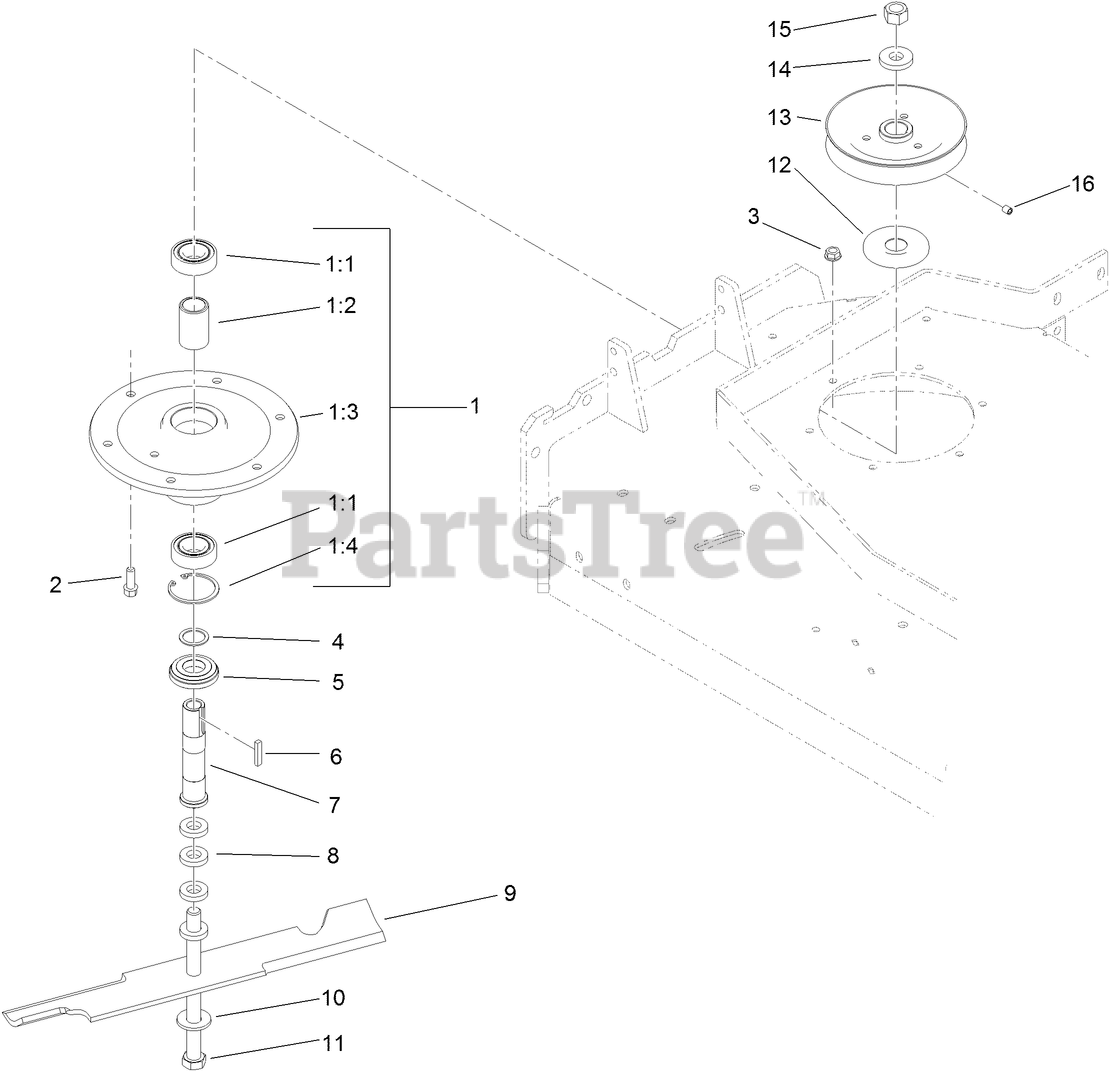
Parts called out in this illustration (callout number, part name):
1	SPINDLE HOUSING ASM
1:1	BEARING-BALL, 1 INCH
1:2	SPACER-BEARING
1:3	HOUSING-SPINDLE
1:4	RING-SNAP
2	SCREW-HWH
3	NUT-HF, NI
4	WASHER-SPACER
5	SPACER-GUARD, BOTTOM
7	TUBE-SPINDLE, SHORT
8	SPACER
9	BLADE-18IN, HI FLOW
10	WASHER-SPRING
11	SCREW-CAP, HH
12	Guard-Bearing, Top
13	SHEAVE
14	WASHER-RETAINER, SHEAVE
15	NUT-HEX
16	SETSCREW
